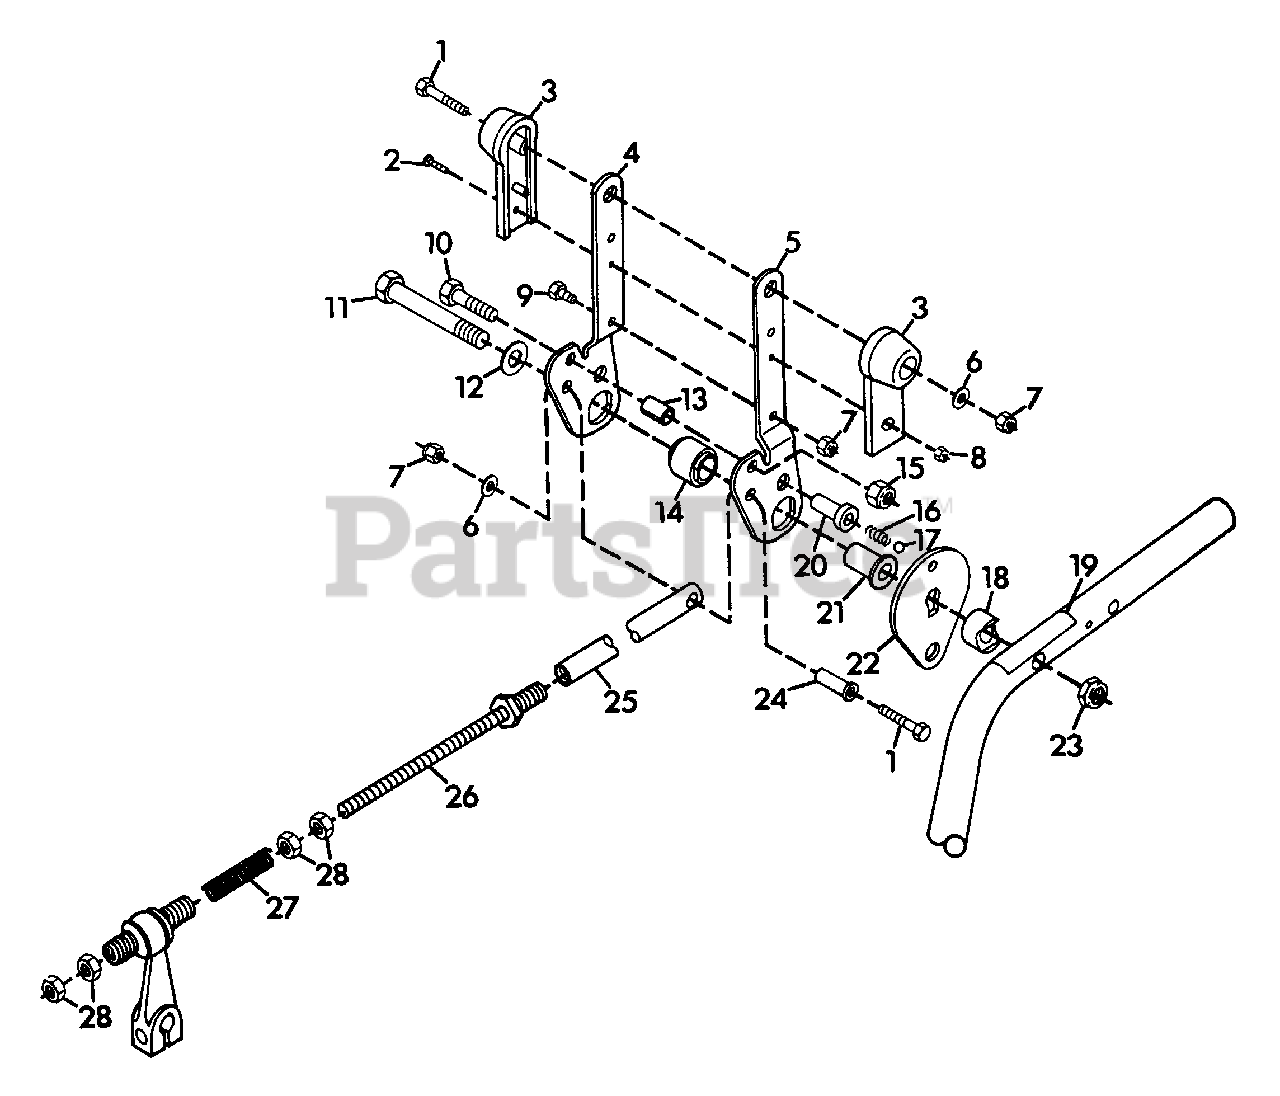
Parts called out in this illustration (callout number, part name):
1	Bolt, Hex 1/4-20 x 1.50
2	Screw, Machine 6-23 x .625
3	Knob, Handle Control
4	Handle, Control R.H.
5	Handle, Control L.H.
6	Washer, Flat .281 x .625 x .065
7	Nut, Lock 1/4-20
8	Nut, Lock 6-32
9	Bolt, Hex 1/4-20 x .625
10	Bolt, Hex 3/8-16 x 1.50
11	Bolt, Hex 1/2-13 x 3.50
12	Washer, Flat .531 x 1.062 x .095
13	Sleeve, Handle Stop
14	Bushing, Handle
15	Nut, Lock 3/8-16
16	Spring, Compression 7/8 x .28
17	Ball, Steel 5/16
18	Bracket, Handle Pivot
19	Decal, Forwar-Reverse
20	Bushing, Neutral
21	Pivot, Handle
22	Plate, Neutral
23	Nut, Lock 1/2-13
24	Bushing, Operator Presence Handle
25	Rod, Control Forward-Reverse
26	Rod, Control Extension
27	Spring, Forward-Reverse Neutral Return
28	Nut, Jam 3/8-16 Hex
